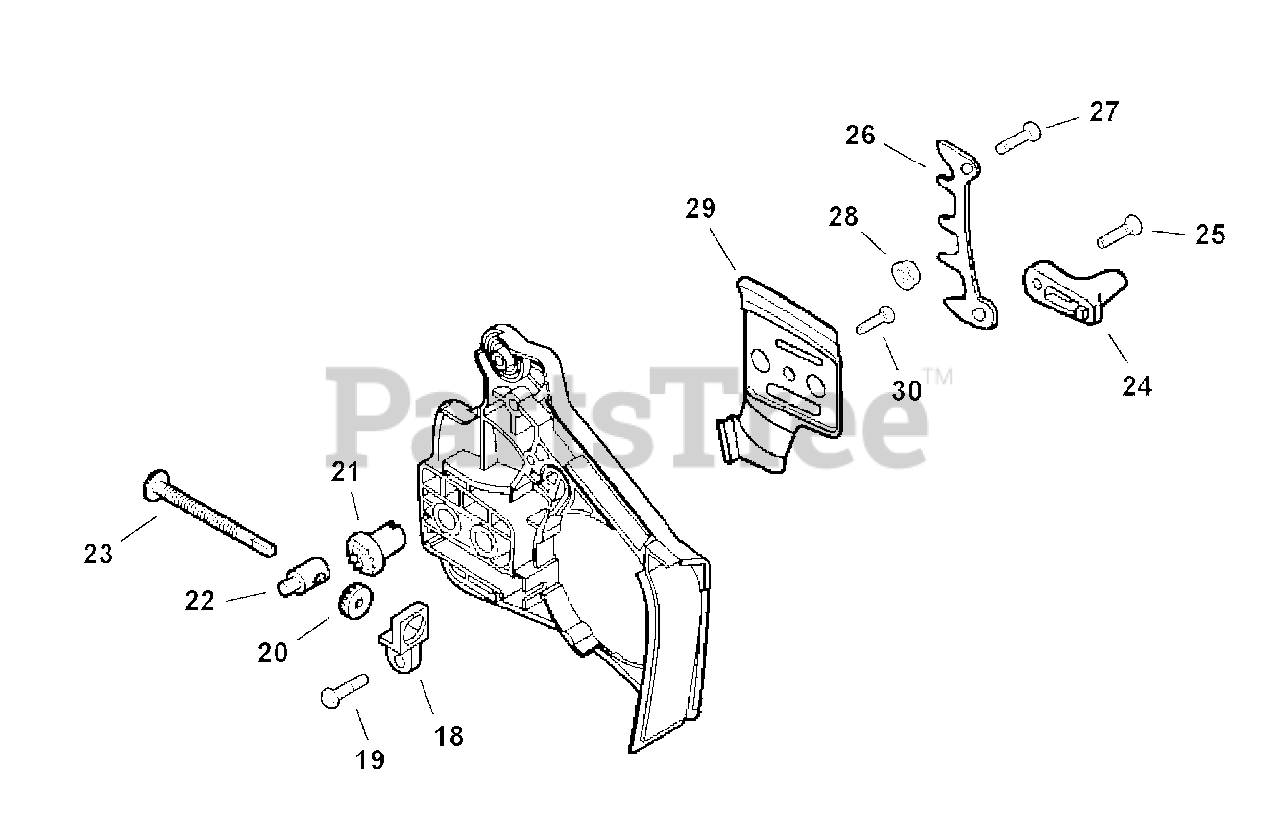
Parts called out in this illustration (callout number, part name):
18	BRACKET, TENSIONER
19	SCREW - 4X12 -- TAPPING
20	GEAR - BEVEL
21	GEAR - PINION
22	TENSIONER, CHAIN
23	SCREW, TENSIONER
24	CATCHER, CHAIN
25	SCREW - 5X20 -- TAPPING
27	SCREW - 5X20 -- TAPPING
28	NUT - 6 -- FLANGE
29	PLATE, GUIDE - INNER
30	SCREW - 4X10
